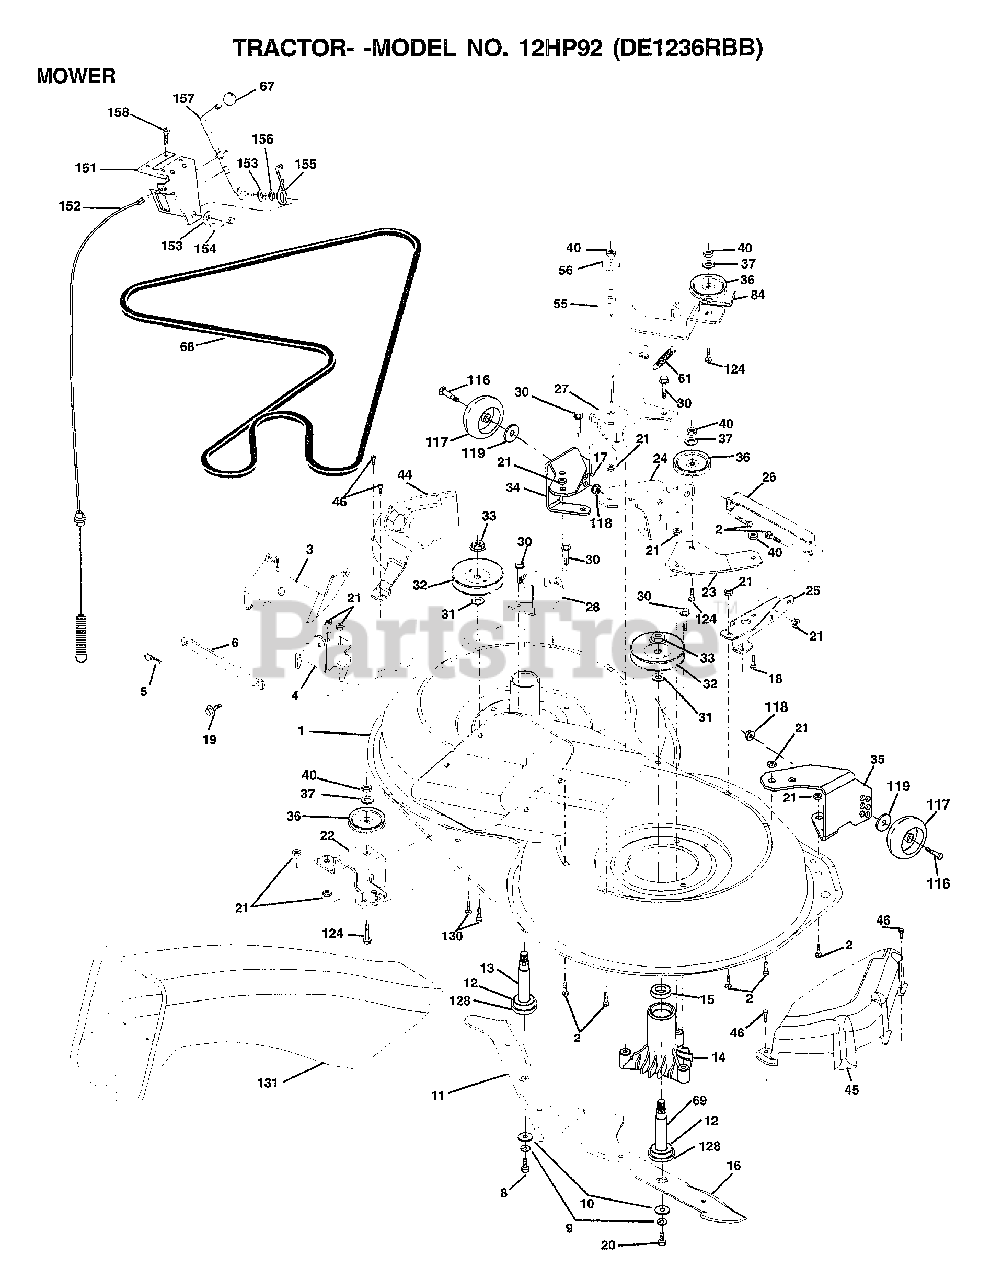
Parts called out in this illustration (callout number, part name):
1	HOUSING.ASM.MOWER
2	BOLT
3	BRKT.ASM.S-BAR.CHASSIS
4	BRKT.BAR.SWAY.DECK
6	BAR.SWAY.92.CRD
8	BLADE BOLT
10	WASHER.HARD.BLADE
11	BLADE
12	BEARING.BALL
14	HSG ASM MANDREL
15	BEARING
16	BLADE
17	BOLT.3/8-14X1.25
18	BOLT D
19	BOLT SHD 5/16-18
20	BOLT.3/8-24X1.25
22	BRKT.IDLER.SPRT.CRD
23	"BRKT.IDLER.SPRT.RF.92,CRD"
24	BRKT.SUSP.LF.92.CRD
25	BRKT.SUSP.RF.92.CRD
26	BRACE.SUPT.SUSP.FRT.CRD
27	BRKT.ASM.SUSP.RR.92.CRD
28	BRKT.ASM.SUSP.LR.92.CRD
30	"SCREW-THD ROLL,WA"
31	WASHER
32	PULLEY.MAND.36/46
34	BRKT.GUAGE.WHL.LF.92.CRD
35	BRKT.GUAGE.WHL.RF.92.CRD
36	PULLEY.IDLER.4.25
37	WASHER
44	COVER.MANDREL.LH.92.CRD
45	COVER.MANDREL.RH.92.CRD
46	SCREW.1/4-20X5/8
55	ARM.IDLER.92.CRD
56	SPACER.RETAINER.MOWER
61	SPRING.TENSION.BELT
67	KNOB T(3/8 HOLE)
68	HEX-BELT.92.MWR.105AA
69	SHAFT.ASM.W/LWR.BRG.RH.THD
84	"KEEPER-BELT,IDLER"
116	BOLT.SHOULDER
117	WHEEL GAGE DONUT
118	LOCKNUT
119	WASHER
124	BOLT.3/8-16X1.50
128	WASHER.FELT.
131	CHUTE.BAGGER.CRD
151	BRKT CLUTCH CABLE
152	CABLE CLUTCH CRD SERVICE
153	WASHER FLAT
154	SPRING RETAINER
155	SPRING RETENTION LVR CLUTCH CAB
156	SPACER
157	ROD.CLUTCH.CABLE.3/8
158	SCREW LT
